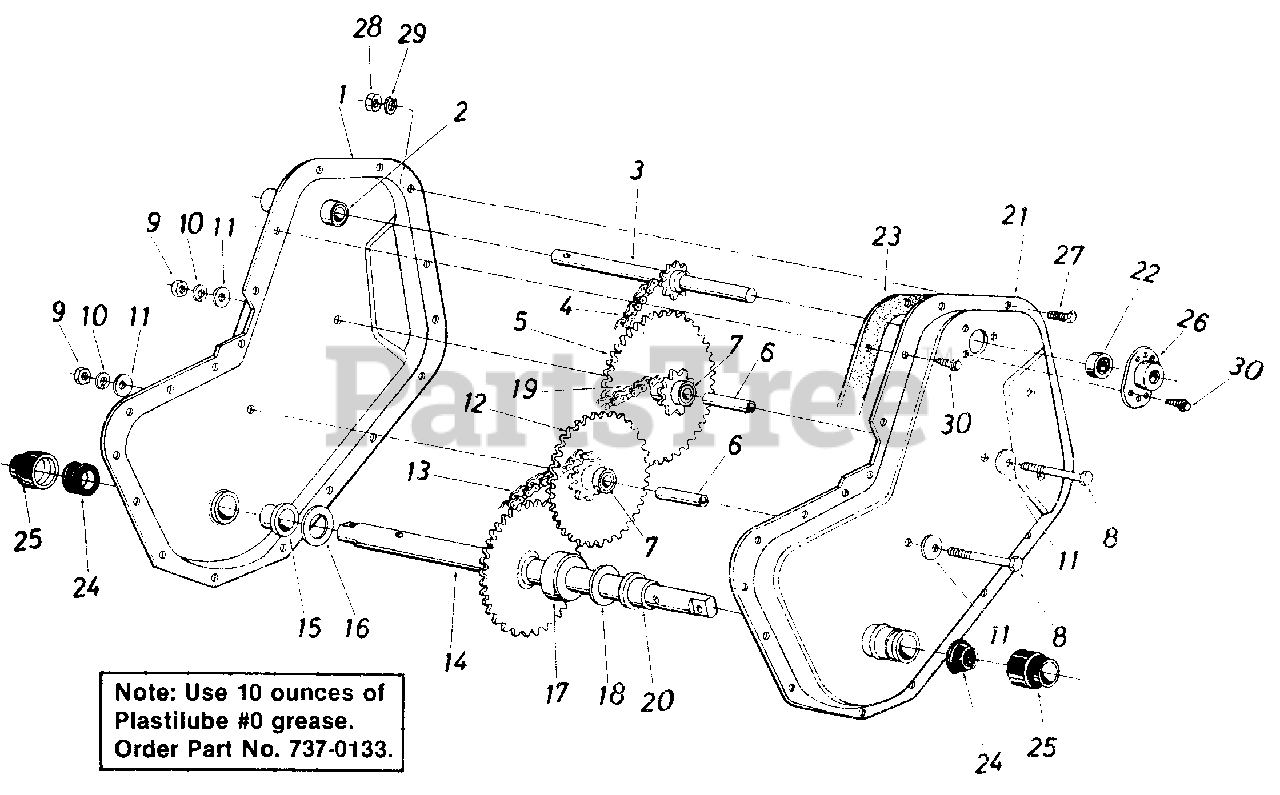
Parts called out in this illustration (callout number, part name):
1	Chain Case Half Ass'y. - R.H.
2	Bearing 5/8" I.D. x .813" O.D. x 1.31" Lg.
3	Input Shaft Ass'y.
4	Chain #35 - 3/8" Pitch x 44 Links
5	Sprocket and Hub Ass'y.
6	Bearing Inner Axle
7	Sleeve Brg. 5/8" I.D. x 3/4" O.D. x 1.50
8	Hex Bolt 3/8-24 x 2.50" Lg.
9	Hex Ins. L-Nut 3/8-24 Thd.
10	L-Wash. 3/8" I.D.
11	Bell-Wash. .41" I.D. x 1.13" O.D. x .03
12	Sprocket & Hub Ass'y. 9T-22T
13	#420 Chain 1/2 Pitch x 28 Links Endless
14	Wheel Shaft Ass'y.
15	Flange Bearing
16	Fl-Wash. .88" I.D. x 1.5" O.D. x .03
17	Spacer 7/8" I.D. x 1 3/4" O.D. x .68" Lg.
18	Fl-Wash. .88" I.D. x 1.50" O.D. x .03
19	#420 Chain 1/2" Pitch x 30 Links Endless
20	Flange Bearing
23	Gasket
26	Bearing Housing
27	Hex Bolt 1/4-28 x 5/8" Lg.
28	Hex Nut 1/4-28 Thd.
29	L-Wash. 1/4" I.D.
30	Hex Wash. S-Tap Scr. 1/4-20 x .50" Lg.
